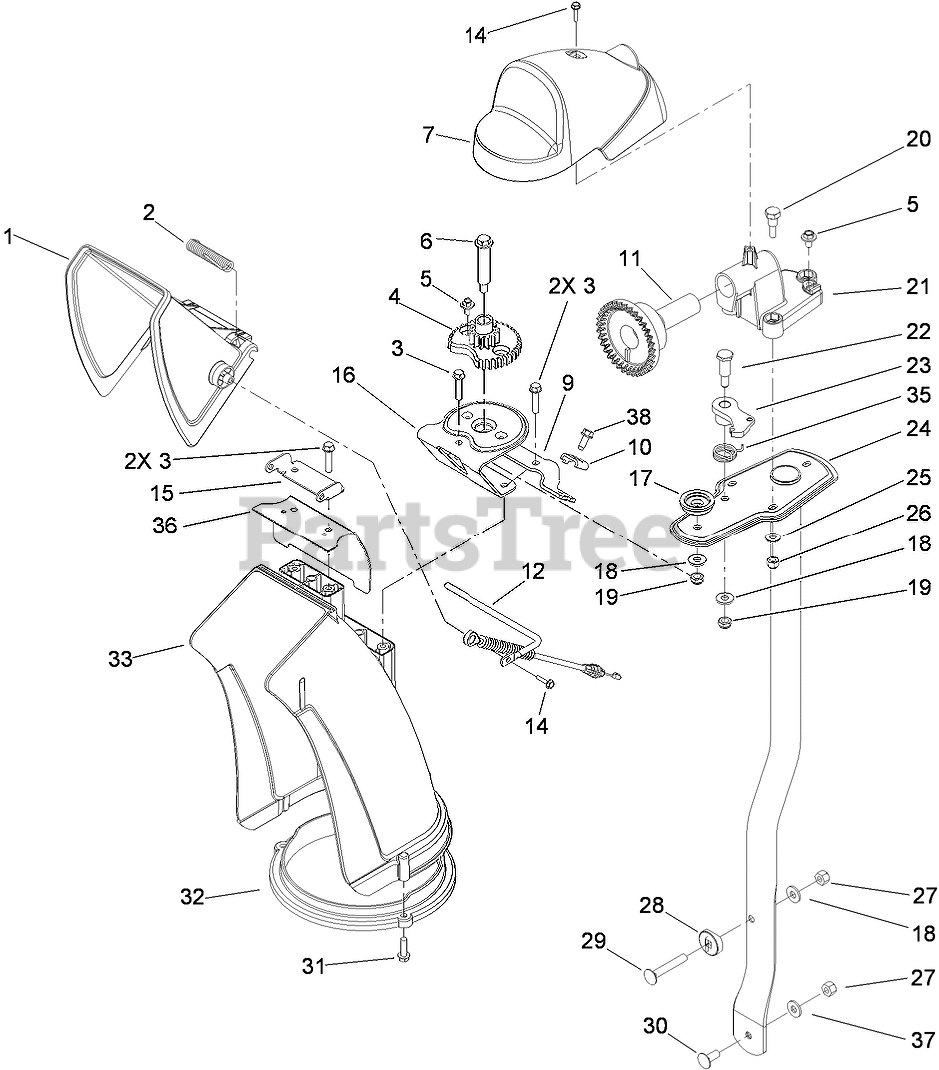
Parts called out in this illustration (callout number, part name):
1	DEFLECTOR-CHUTE, CE
2	SPRING-TORSION
3	SCREW-PLASTITE
4	GEAR-CHUTE
5	SCREW AND WASHER ASM
6	BOLT-SHOULDER
7	COVER-GEAR, CHUTE
9	BRACKET-CABLE, CLAMP
10	CLAMP-CABLE
11	GEAR-FACE
12	ROD-DEFLECTOR
14	SCREW-HWH
15	BRACKET-DEFLECTOR
16	BRACKET-SUPPORT, CHUTE
17	SPACER-CHUTE
18	WASHER-FLAT
19	NUT-LOCK, NI
20	SCREW-SHOULDER
21	MOUNT-GEAR, FACE
22	SCREW-SHOULDER
23	LATCH-CHUTE
24	TUBE-SUPPORT
25	WASHER-FLAT
26	NUT-LOCK, NI
27	NUT-LOCK, NI
28	WASHER-CURVED
29	SCREW-CARR
30	SCREW-CARR
31	SCREW-HWH
32	RING-CHUTE
33	CHUTE-DISCHARGE
35	SPRING-TORSION
36	SEAL-CHUTE
37	WASHER-BELLEVILLE
38	SCREW-HWH
